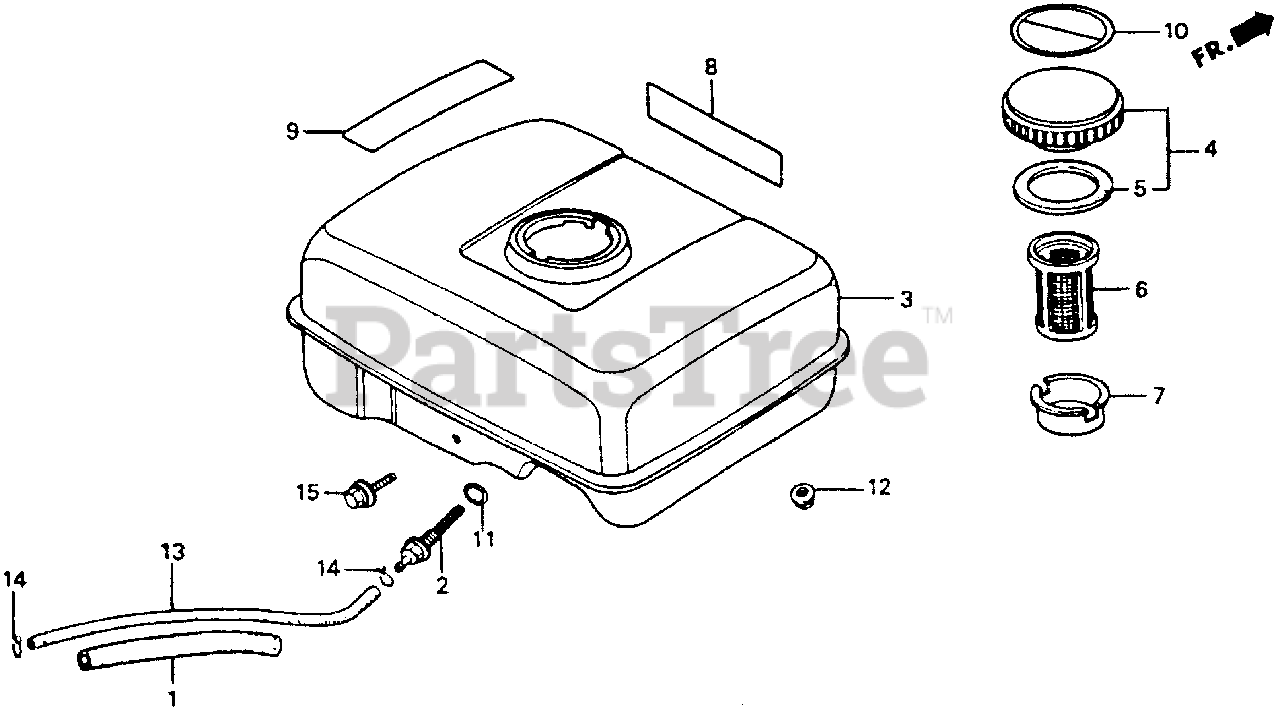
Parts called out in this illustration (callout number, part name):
1	RUBBER, SUPPORTER (107MM)
2	JOINT, FUEL TANK
3	TANK, FUEL *NH31* (MCKINLEY WHITE)
4	CAP, FUEL FILLER (BLACK)
5	GASKET, FUEL FILLER CAP (39X58X3)
6	FILTER, FUEL
7	HOLDER, FUEL FILTER
8	MARK (WB20X)
9	MARK, CAUTION (PUMP)
10	MARK, CAUTION
11	O-RING (14MM) (ARAI)
12	NUT, FLANGE (6MM)
13	BULK HOSE, FUEL (4.5X3000) (4.5X140)
14	CLIP, TUBE (B8)
15	BOLT, FLANGE (6X25)
